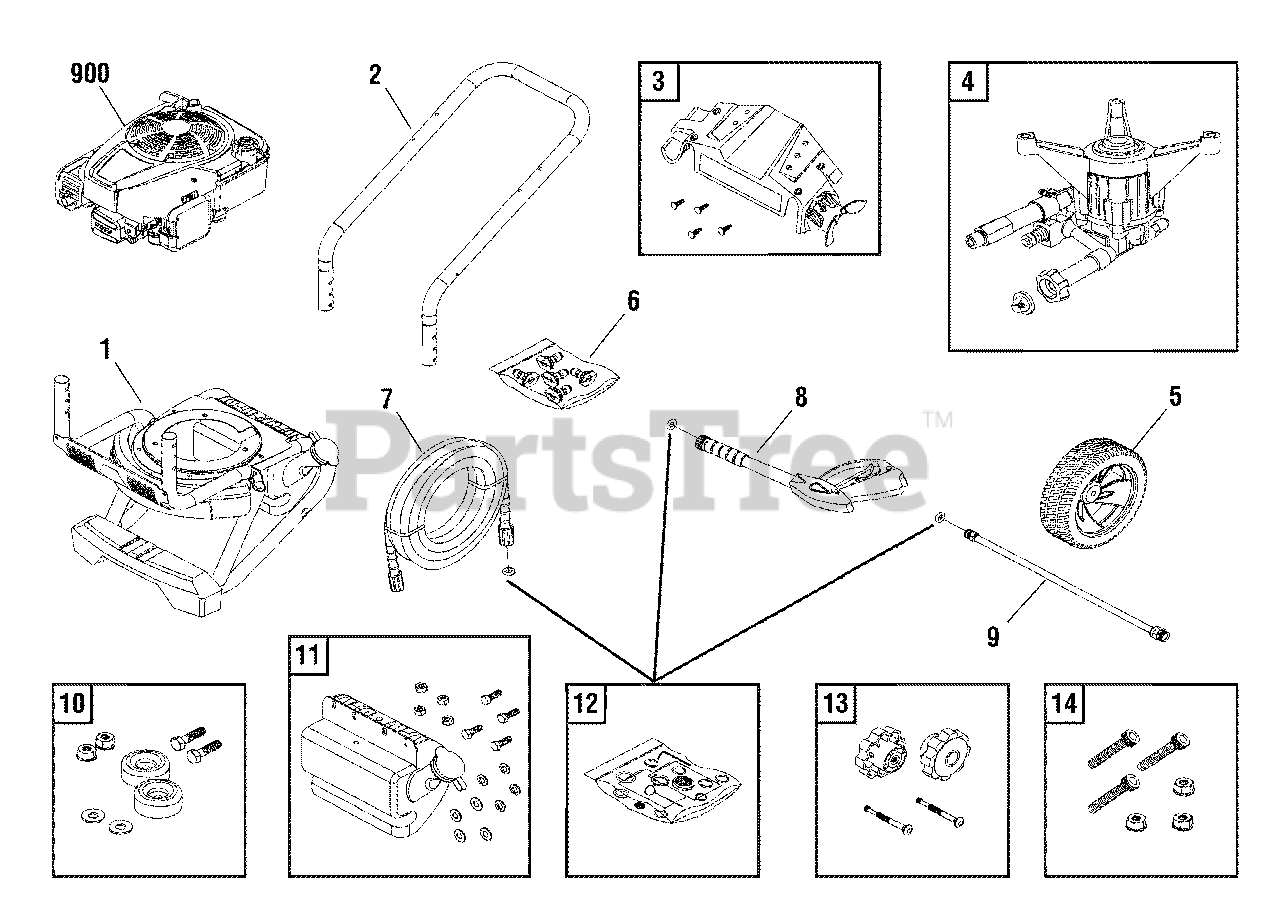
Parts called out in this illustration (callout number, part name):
6	KIT, QC Nozzles
7	HOSE
8	GUN
9	EXTENSION, QC
10	MOUNT, Vibration
12	KIT, O-Rings
13	KIT, Hardware, Handle
14	KIT, Hardware, Pump Mounting
900	* ENGINE
